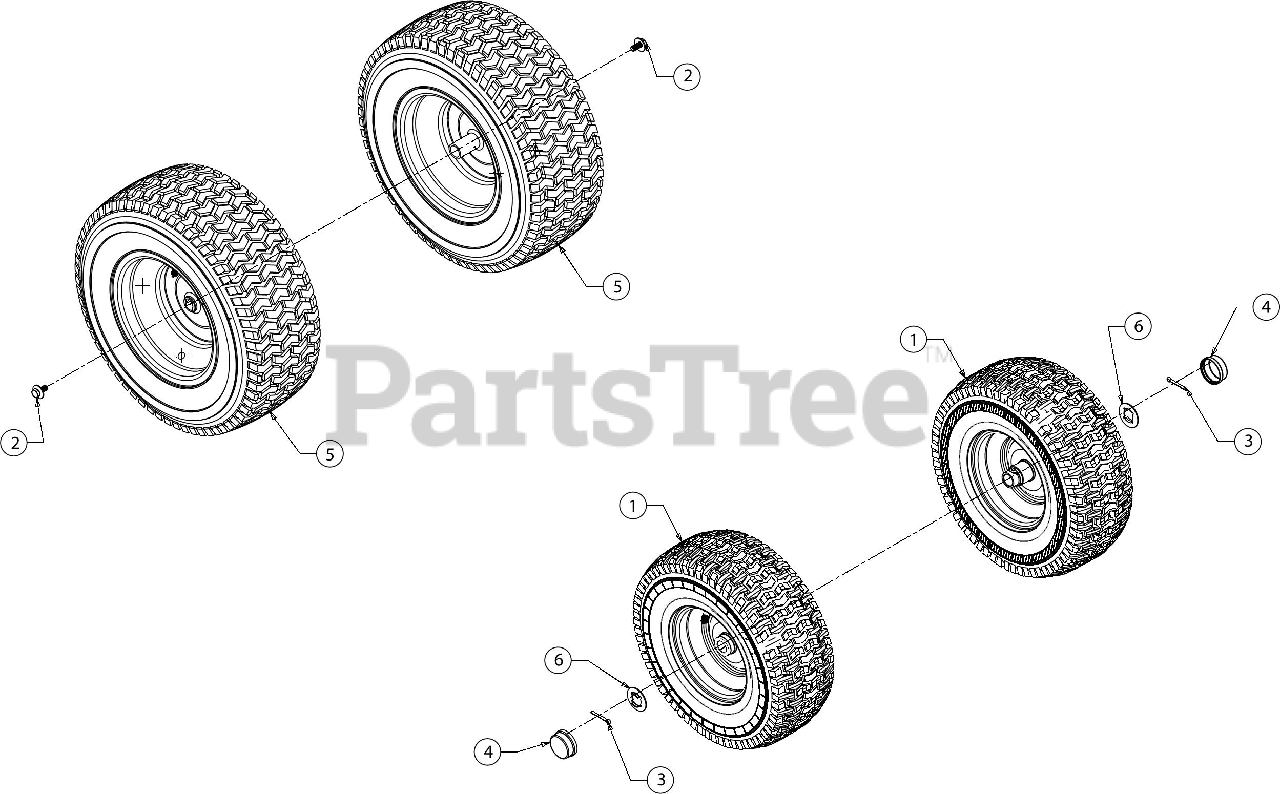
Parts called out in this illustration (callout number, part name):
1	WHEEL ASSEMBLY (13 x 5 x 6) (OYSTER-DELI)
2	SCREW 5/16-24 x .750 GR5
3	COTTER PIN-5/32 DIA
4	HUB CAP-BLACK
5	WHEEL ASSEMBLY
6	FLAT WASHER .781 ID x1.590 OD
